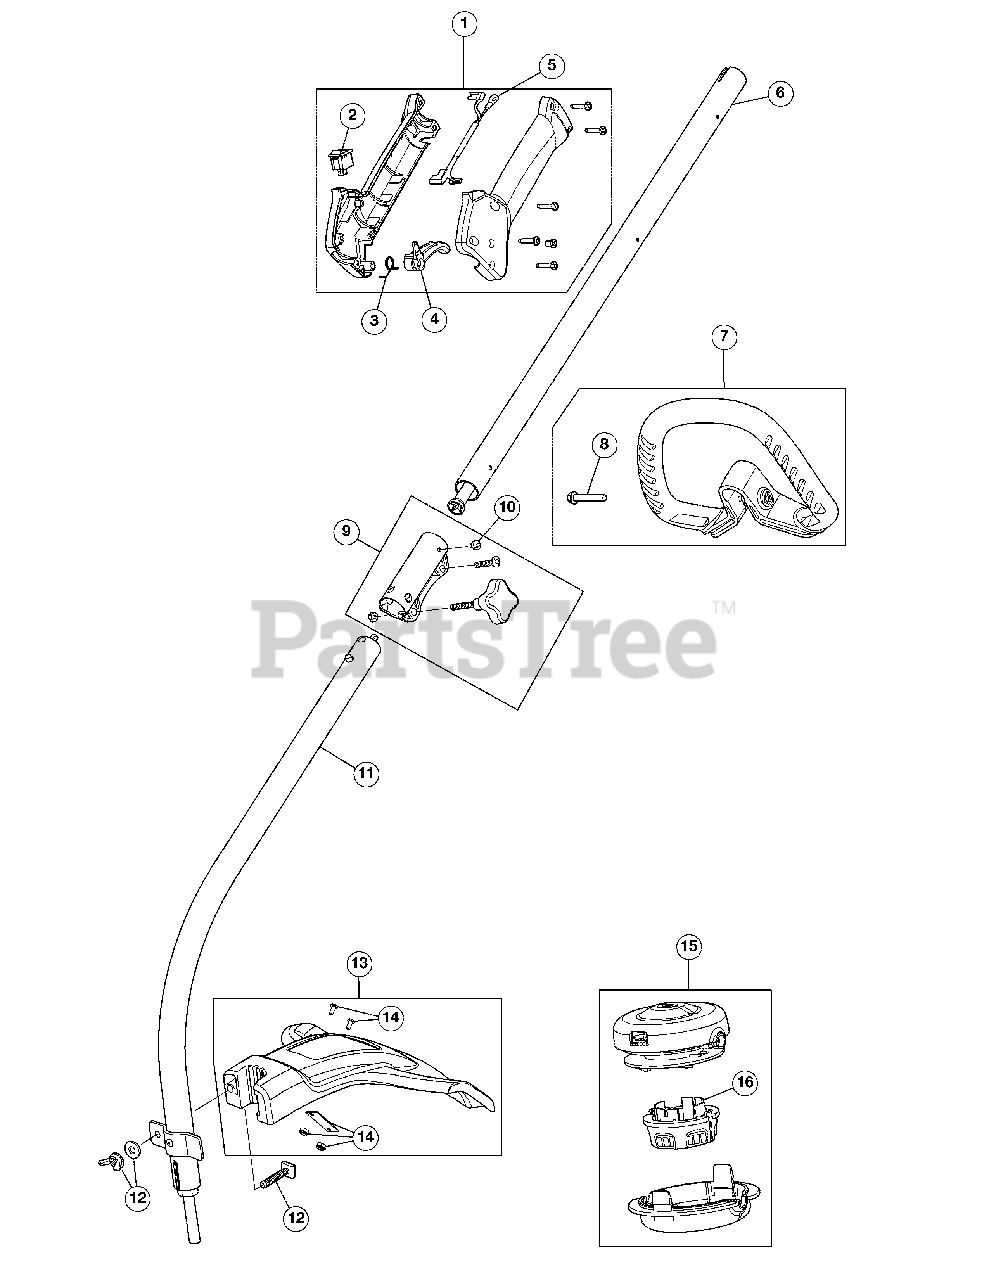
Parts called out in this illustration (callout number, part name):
1	Throttle Housing Assembly (Incl. 2 - 4)
2	Switch Assembly
3	Throttle Trigger Spring
4	Throttle Trigger
5	Throttle Cable Assembly
6	Upper Drive Shaft Housing Assembly
7	D-Handle Assembly (Incl. 8)
9	Split Boom Coupler (Incl. 10)
10	Coupler Anti-Rotation Screw
11	Lower Drive Shaft Housing Assembly
12	Shield Mounting Hardware
13	Shield Assembly (Incl. 14)
14	Blade Assembly
15	Cutting Head Assembly (Incl. 16)
16	Bump Knob
